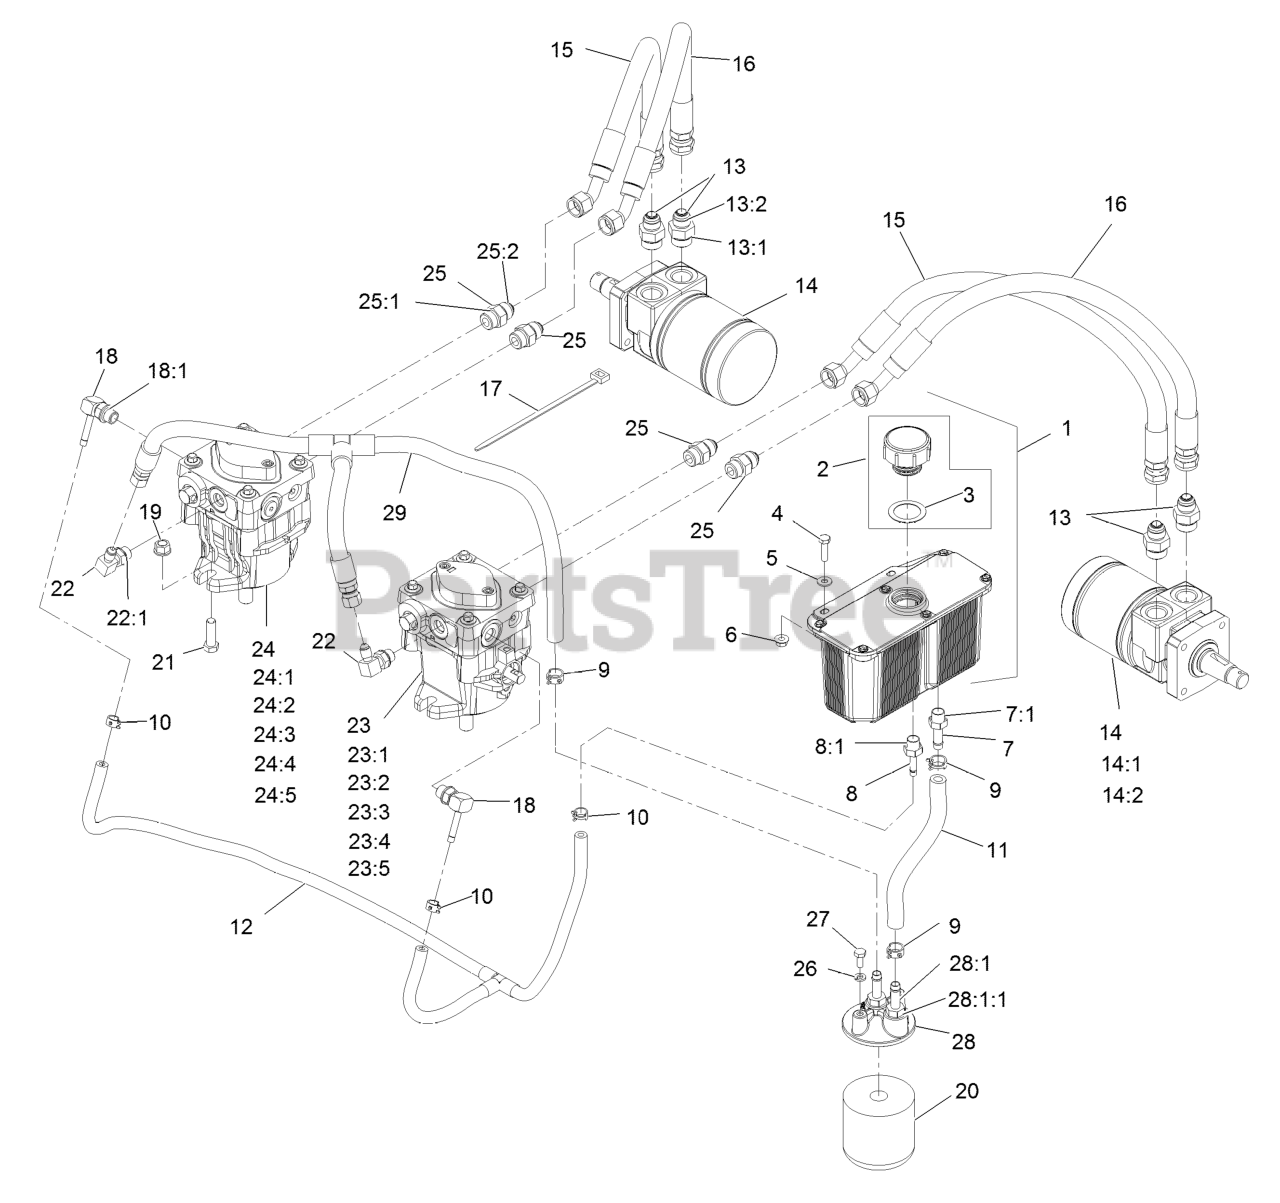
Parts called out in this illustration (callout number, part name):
1	HYD RESERVOIR ASM
2	KIT,HYD RES CAP W/GASKET
3	GASKET-CAP
4	SCREW-HH
5	WASHER-FLAT
7	ADAPTER-STRAIGHT
8	ADAPTER-STRAIGHT
9	CLAMP-HOSE
10	CLAMP-HOSE
11	HOSE,CASE DRAIN RH
12	ASM,CASE DRAIN HOSE
13	FITTING-STRAIGHT
14	HYD MOTOR ASM
14:1	SEAL KIT
14:2	BEARING AND SEAL KIT
15	HOSE,HYDRAULIC W/COVER
16	HOSE,HYDRAULIC W/COVER
17	TIE-PLASTIC
18	ELBOW-90 DEG
19	NUT-FLANGE
20	FILTER-25 MICRON, BI-DIRE
20	ELEMENT-FILTER, WINTER
21	SCREW-HH
22	FITTING-ELBOW, 90 DEG
23	PUMP-HYD PE RH TTH
23:1	INPUT SHAFT KIT
23:2	BEARING-THRUST
23:3	CYLINDER BLOCK KIT
23:4	SEAL OVERHAUL KIT
23:5	KIT, 10CC PUMP KIT
24	PUMP-HYD PE LH TTH
24:1	INPUT SHAFT KIT
24:2	BEARING-THRUST
24:3	CYLINDER BLOCK KIT
24:4	SEAL OVERHAUL KIT
24:5	KIT, 10CC PUMP KIT
25	FITTING-STRAIGHT
26	WASHER-LOCK
27	SCREW-HH
28	FILTER HEAD ASM
28:1	ADAPTER-STRAIGHT
29	ASM,CHARGE HOSE
